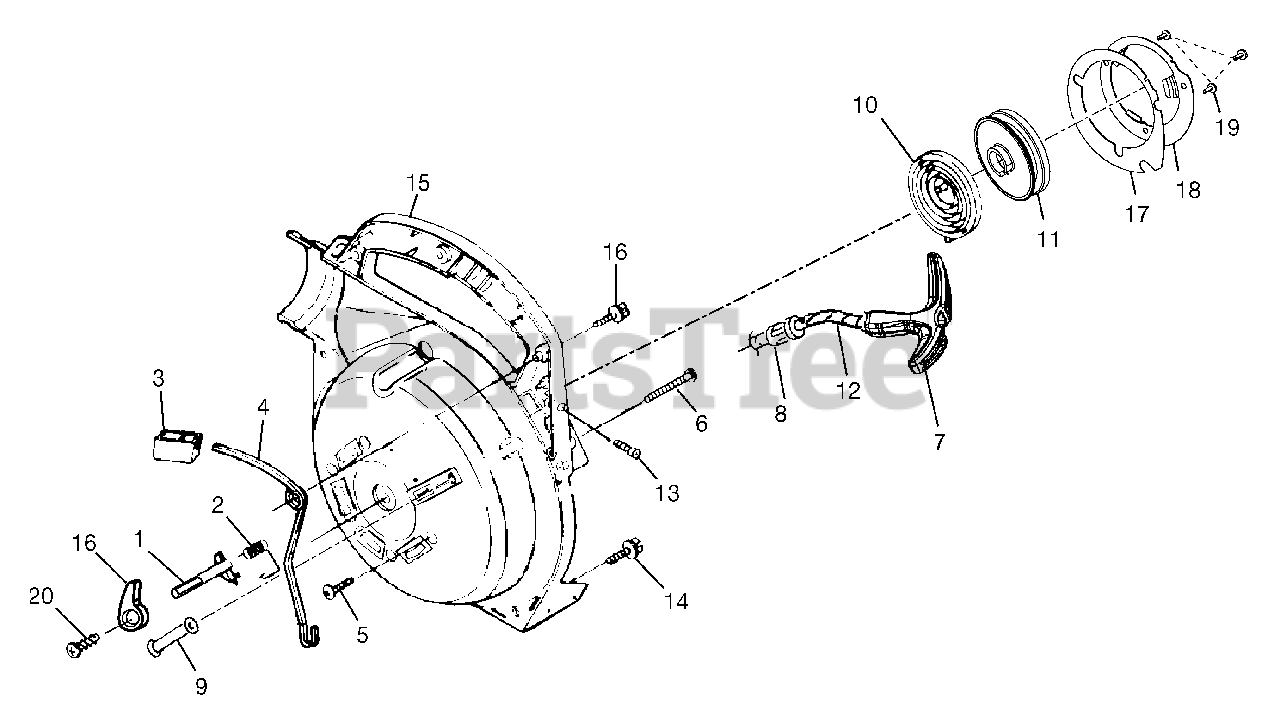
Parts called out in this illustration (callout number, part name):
1	THROTTLE LATCH
2	THROTTLE LATCH SPRING
3	THROTTLE TRIGGER
4	THROTTLE LEVER
5	SCREW (10-24 x 3/4 in TRUSS HD)
6	SCREW (10 x 1-5/8 in HEX HD)
7	STARTER GRIP (YELLOW)
8	BUSHING STARTER
9	STARTER ROPE GUIDE
10	SPRING AND CONTAINER
11	PULLEY ASSEMBLY
12	STARTER ROPE
13	SCREW (8-32 x 5/8 in FIL HD)
14	SCREW (10-14 x 3/4 in TORX TRUSS HD)
15	INNER VOLUTE HOUSING
16	THROTTLE CONTROL KNOB
17	BAFFLE GASKET
18	BAFFLE PLATE
19	SCREW (#8-16 X 1/2 in)
20	SCREW (10-14 X 1/2 in TORX)
